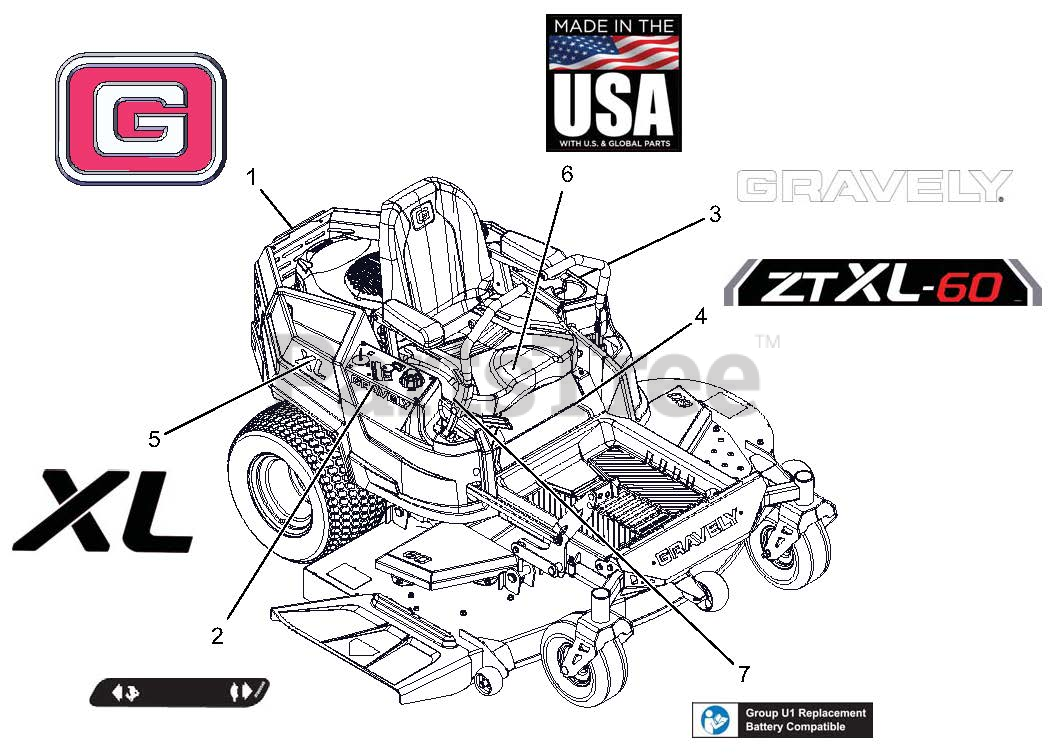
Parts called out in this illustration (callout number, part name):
1	DECAL, GRAVELY BRAND
2	DECAL, DASH DECAL
3	DECAL, 9.5" GRAVELY LOGO
4	DECAL, ZTXL 60
5	DECAL, "XL"
6	DECAL, MADE IN USA
7	DECAL, U1 BATTERY REPLACEMENT
